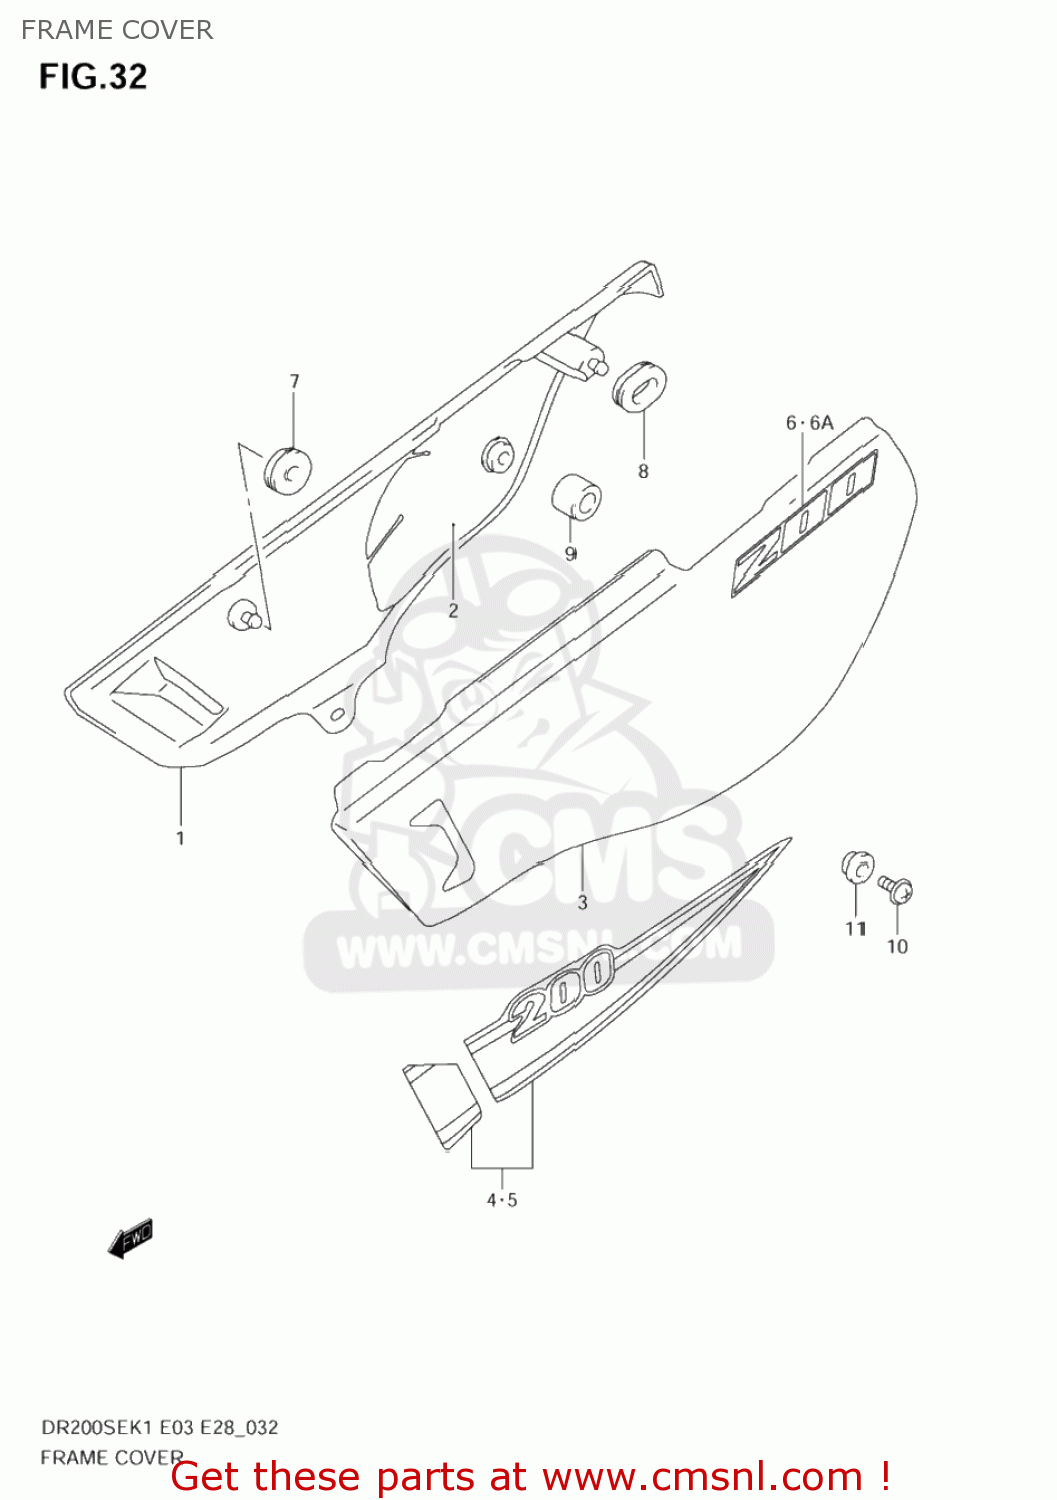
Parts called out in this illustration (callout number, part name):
1	COVER,FRAME,R(WHITE)
2	SHIELD,FRAME COVER,R
3	COVER,FRAME,L(WHITE)
4	TAPE,FRAME COVER,R
5	TAPE,FRAME COVER,L
6	EMBLEM,FRAME COVER
6A	EMBLEM,FRAME COVER
7	CUSHION
8	CUSHION
9	CUSHION
10	SCREW(6X16)
11	WASHER
